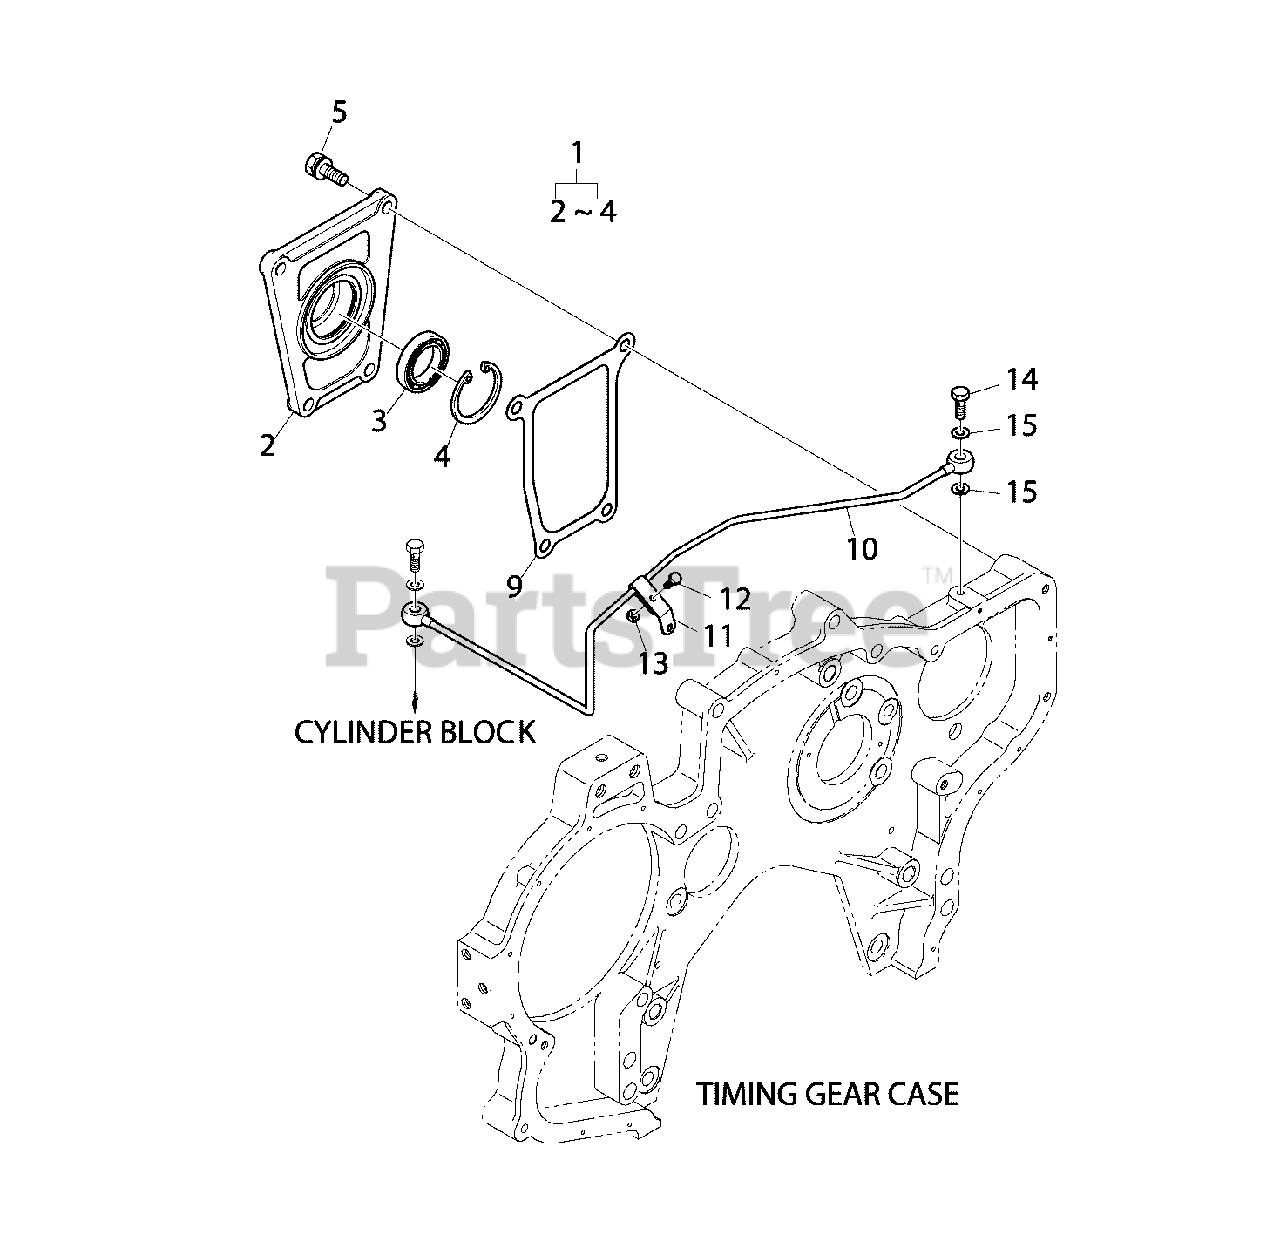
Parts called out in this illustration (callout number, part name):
1	* END COVER
2	* END COVER
3	* BEARING, BALL
4	* RING, SNAP
5	* BOLT
9	* GASKET, AIR COMPRESSOR
10	* PIPE, OIL
11	* CLIP
12	* BOLT, HEX
13	* NUT, HEX
14	* SCREW
15	* RING, SEAL
